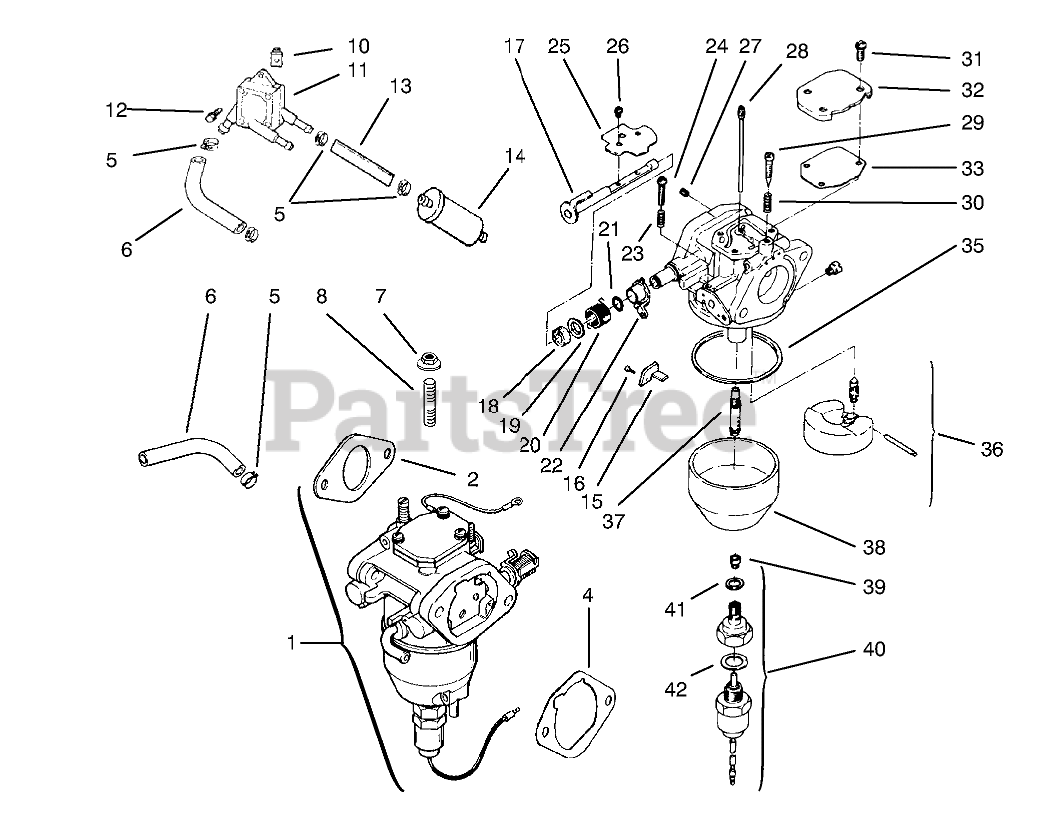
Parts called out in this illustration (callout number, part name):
2	Kit-Carburetor
4	Gasket-A/C Base
5	Clamp
6	Line-Fuel
7	Nut
10	Nut
11	Pump-Fuel
12	Screw
13	Line-Fuel
14	Filter-Fuel
15	Bracket-Throttle Stop
16	Screw
17	Shaft-Choke
18	Washer
19	Collar-Coke
20	Spring-Choke Return
21	Ring-Choke Lever
22	Lever-Choke
23	Sprin-Throttle Screw
24	Screw-Throttle Adjust
25	Valve-Choke
26	Screw
27	Jet-Air Bleed
28	Jet-Slow
29	Screw
30	Spring-idler Screw
31	Screw
32	Cover-Passage
33	Gasket-PassageCover
35	Gasket-FloatChamber
36	Kit-Float Repair
37	Nozzle-Main
38	Chamber-Float
39	Jet-Main
40	Kit-Solenoid INC41-42
41	Gasket-ChamberScrew
42	Gasket-Solenoid
